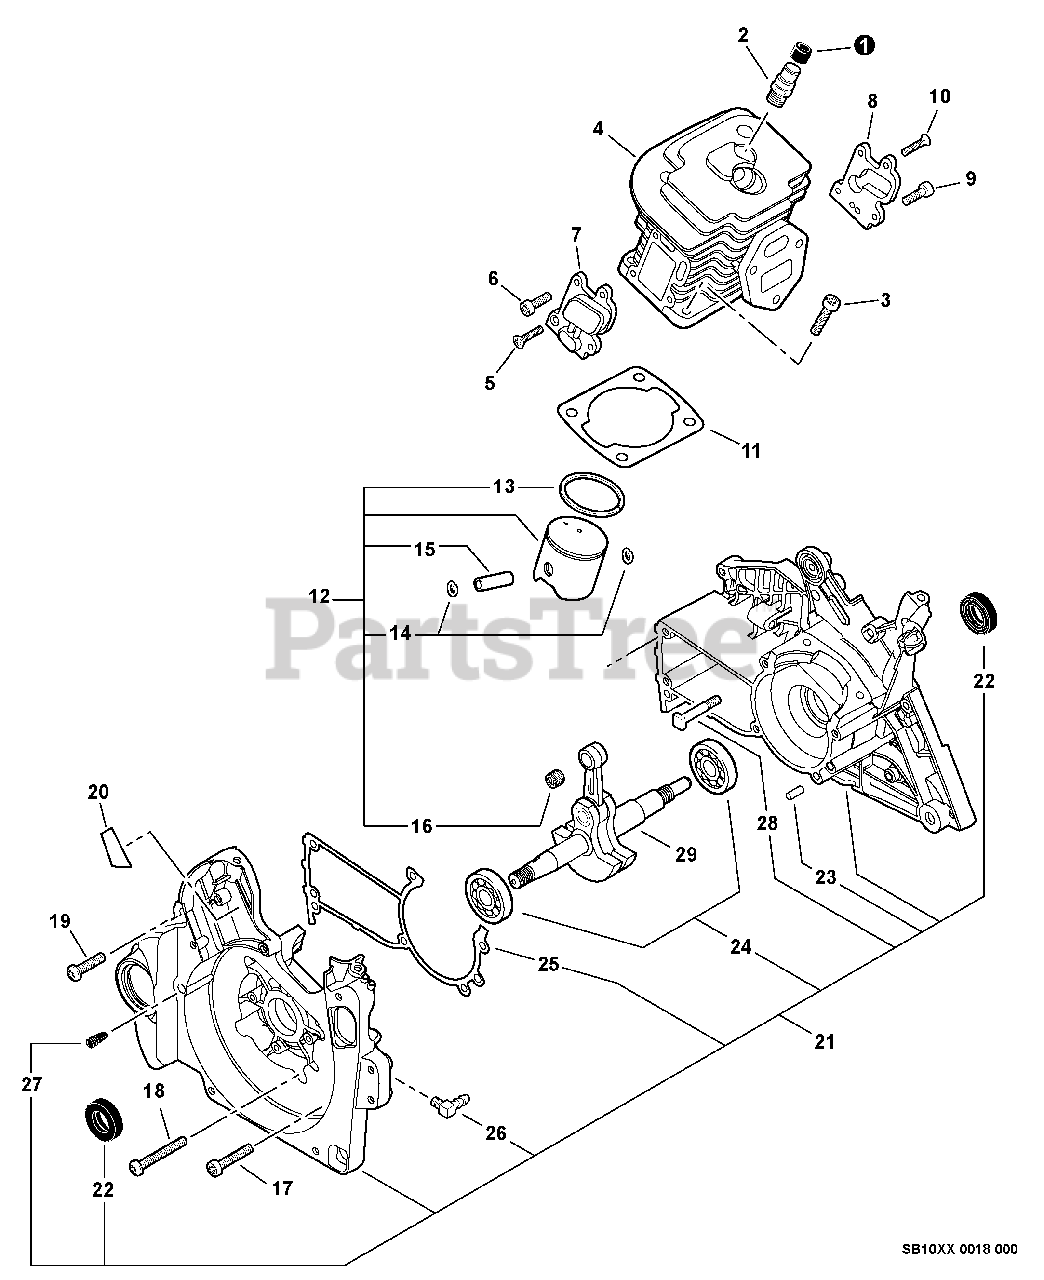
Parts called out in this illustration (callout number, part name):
1	COVER, DUST
2	DECOMPRESSION ASSY
3	SCREW - 5X25
4	CYLINDER
5	SCREW - 4X14
6	SCREW - 4X12
7	REED VALVE ASSY - LEFT
8	REED VALVE ASSY - RIGHT
9	SCREW - 4X12
10	SCREW - 4X14
11	GASKET, CYLINDER
12	PISTON KIT
13	RING, PISTON
14	RING, RETAINING
15	PIN, PISTON
16	BEARING, NEEDLE
17	SCREW - 5X25
18	SCREW - 5X35 -- TAPPING
19	SCREW - 5X20
20	CUSHION
21	CRANKCASE KIT
22	SEAL, OIL
23	PIN - LOCATING
24	BEARING, BALL - 6202
25	GASKET, CRANKCASE
26	FITTING, GREASE
27	VENT, TANK
28	STUD, GUIDE BAR
29	CRANKSHAFT ASSY
